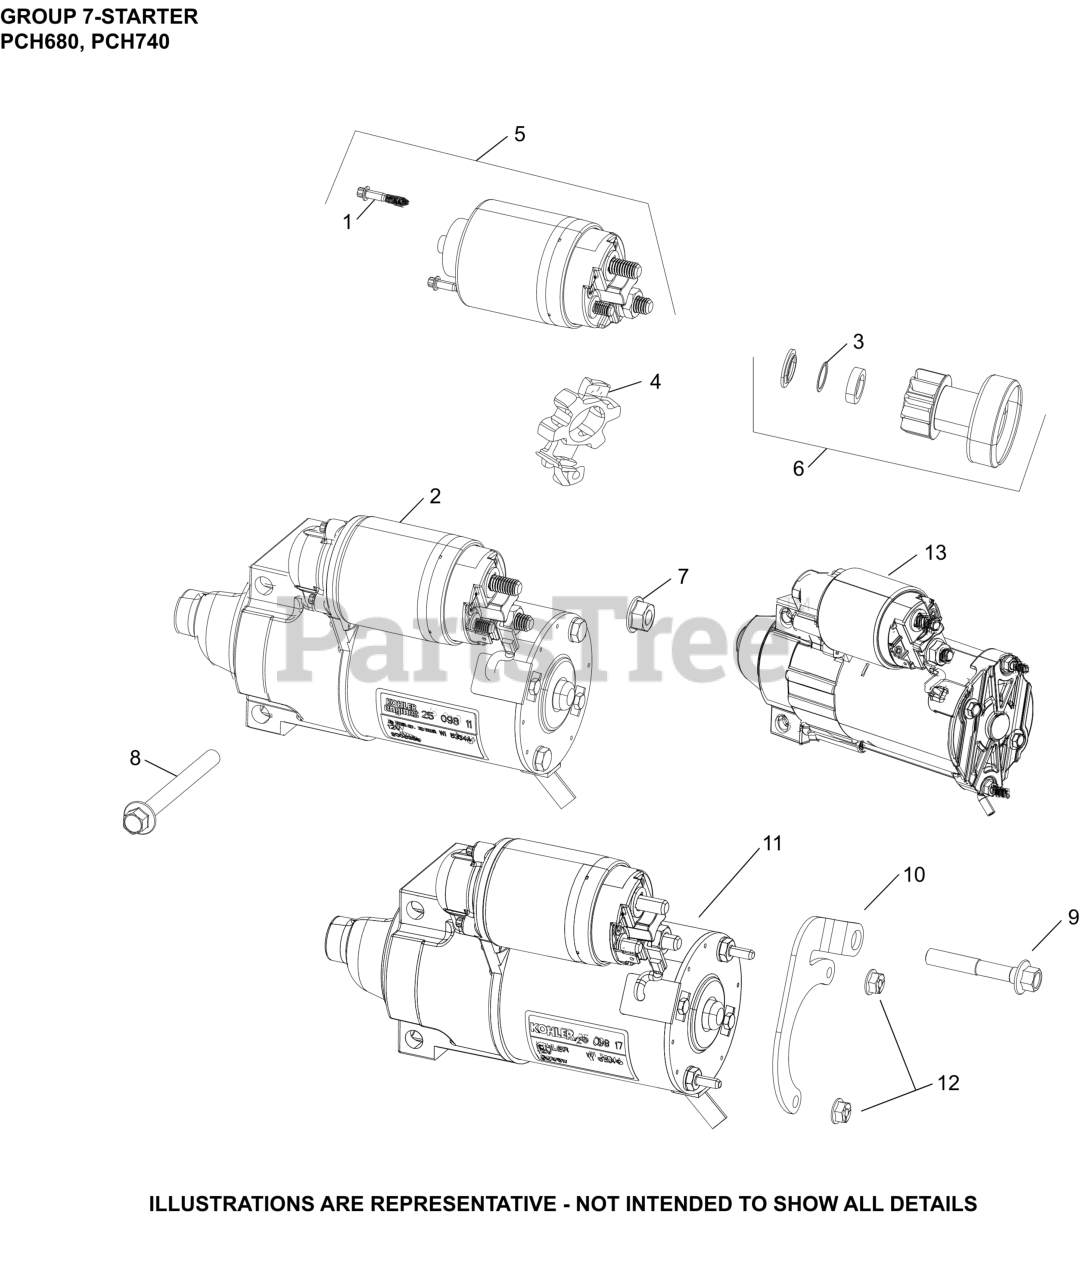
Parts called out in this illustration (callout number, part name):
7	NUT, FLG M8X1.25
8	SCREW, FLG M8X1.25X80
NI	STARTER, SOLENOID SHIFT
